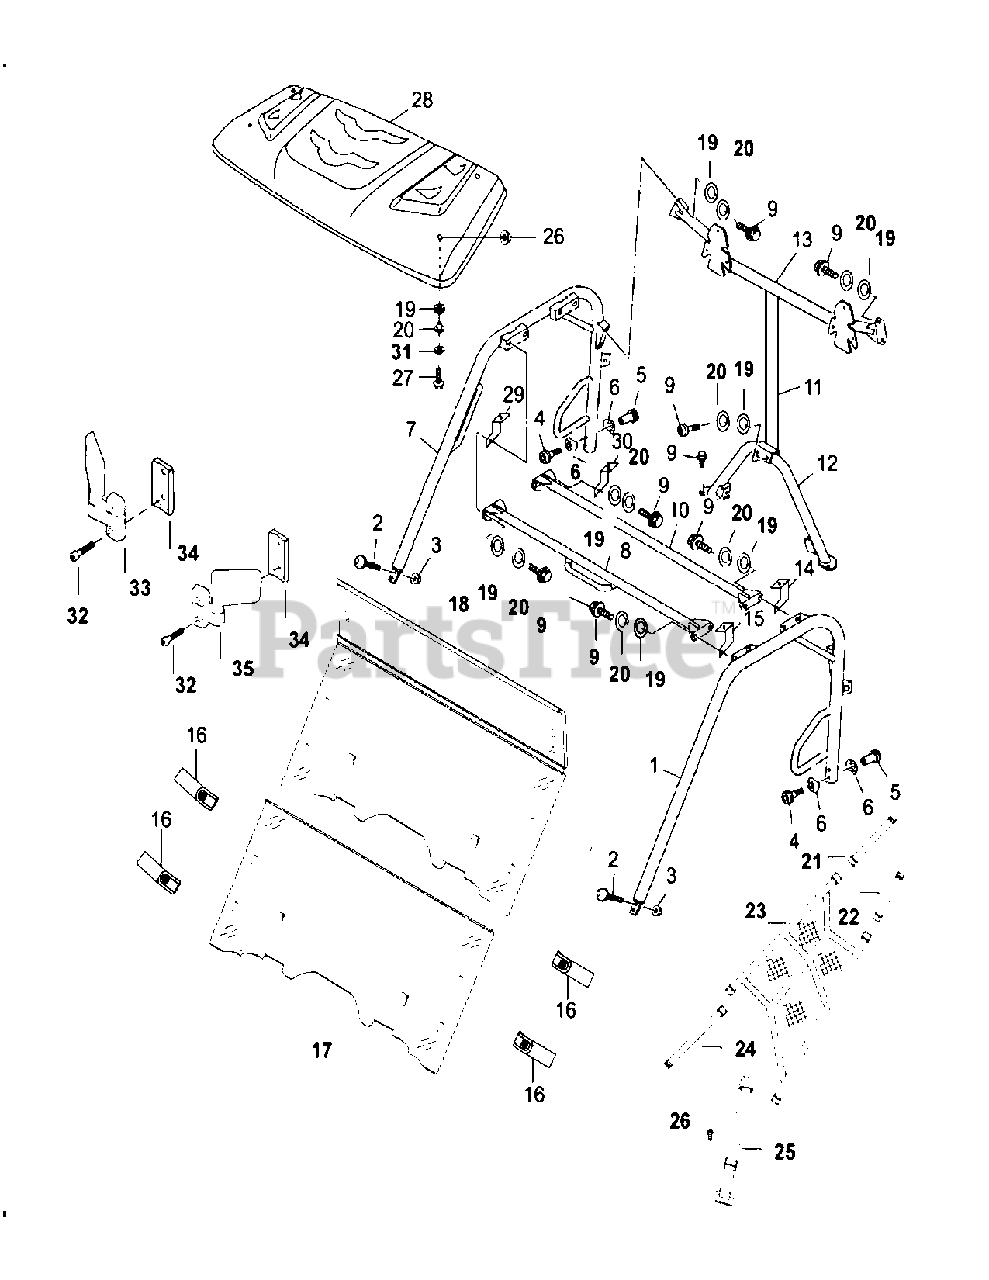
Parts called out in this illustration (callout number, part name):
1	Front Part of Roof Rod (Left)
2	Hexagon Socket Head Screw M10×1.25×45
3	Hexagon flange nut M10×1.25
4	Hexagon Socket Head Bolt M8×22-10×16
5	Hexagon Socket Head Bolt M8×25
6	Curved Washer
7	Front Part of Roof Rod (Right)
8	Horizontal Tube Assy I, Shed
9	Hexagon flange bolt M10×1.25×20
10	Horizontal Tube Assy II, Shed
11	Middle Rod Of Back Rest
12	Headrest Lower Support Bracket
13	Back Rest Support
14	Roof Rear Support (L)
15	Roof Front Support (L)
16	Clamp Assy
17	Front Windshield (Lower)
18	Front Windshield (Upper)
19	Spring washer -10
20	Washer10×20×2
21	Rubber Strip I
22	Rubber Latch II
23	Protective Net
24	Rubber Strip IV
25	Position Return Band III
26	Cross small plate head screw M5×16
27	Hexagon Flange Bolt M6×30
29	Roof Front Support (R)
30	Roof Rear Support (R)
31	Spring Washer -6
32	Hexagon Socket Head Screw M6×30
33	Right Mirror Assy
34	Mirror Mounting Bracket
35	Left Mirror Assy
